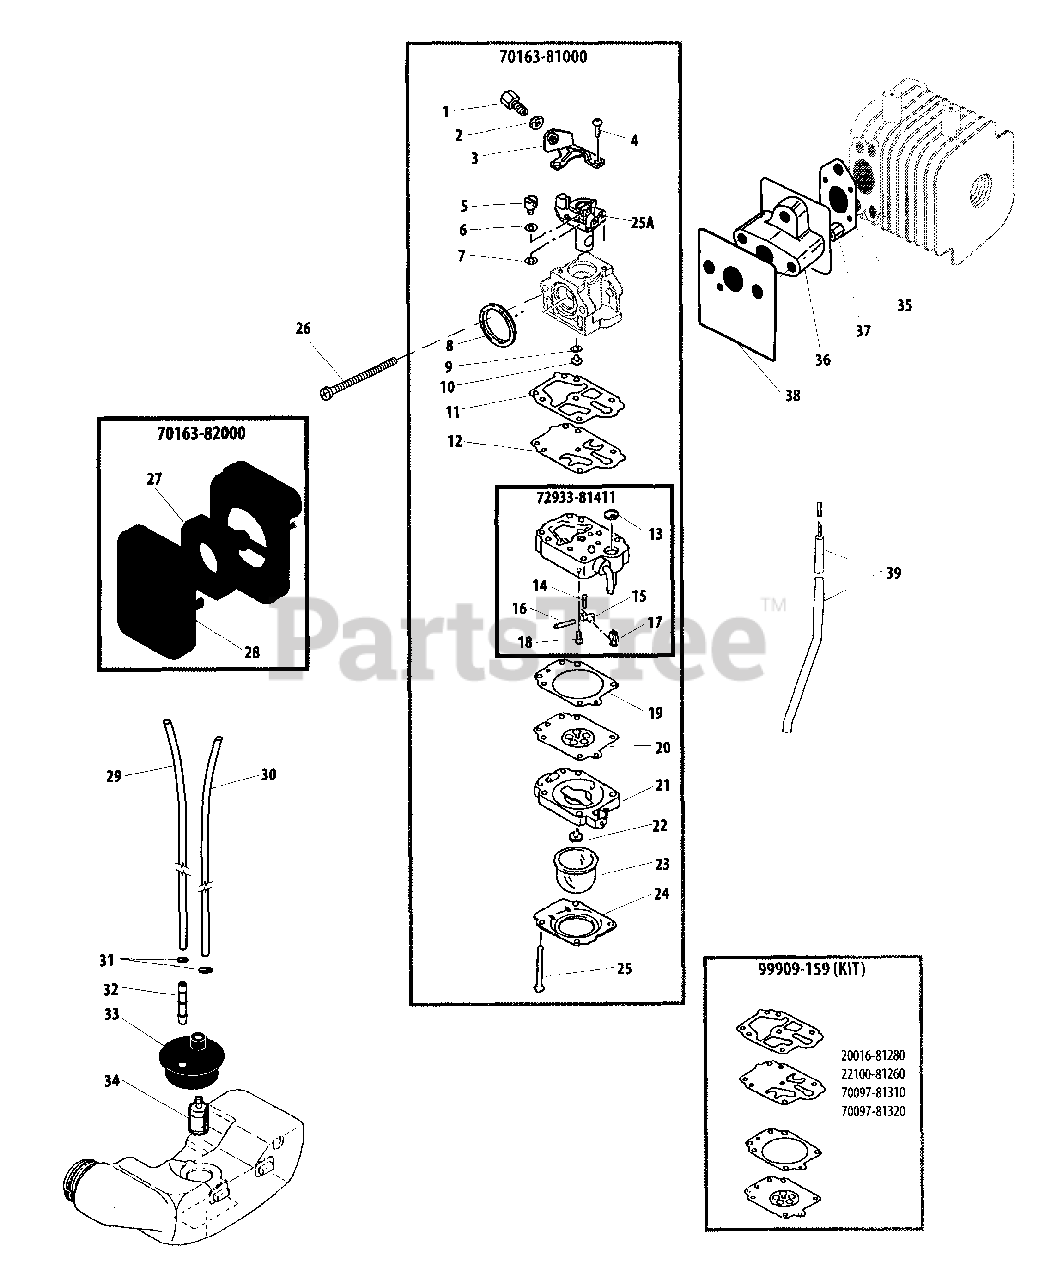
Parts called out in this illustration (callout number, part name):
1	ADJUSTER, THROTTLE CABLE
2	NUT, ADJUSTER LOCK M7
3	BRACKET, THROTTLE CABLE
4	SCREW
5	SWIVEL
6	WASHER
7	E-RING
8	RING, PACKING
9	O-RING
10	MAIN JET (#37)
11	GASKET, PUMP
12	DIAPHRAGM, PUMP
13	SCREEN, FUEL INLET
14	SPRING, METERING LEVER
15	LEVER, METERING
16	PIN, METERING LEVER
17	VALVE, INLET NEEDLE
18	SCREW
19	GASKET, METERING DIAPHRAGM
20	DIAPHRAGM, METERING
21	BODY ASSY, PURGE
22	VALVE, CHECK
23	BULB, PURGE
24	RETAINER, PURGE BULB
25	SCREW
25A	THROTTLE VALVE ASSY
27	FILTER, AIR
28	COVER, AIR FILTER
29	PIPE, RETURN
30	PIPE, FUEL
31	CLIP Ø6
32	CONNECTOR, PIPE
33	GROMMET
34	FILTER, FUEL 125-528
36	INSULATOR
37	NUT M5×6.3
38	GASKET
39	CABLE, THROTTLE
70163-81000	CARBURETOR
70163-82000	AIR FILTER CASE ASSY
72933-81411	BODY ASSY, PUMP
99909-159	GASKET / DIAPHRAGM KIT
